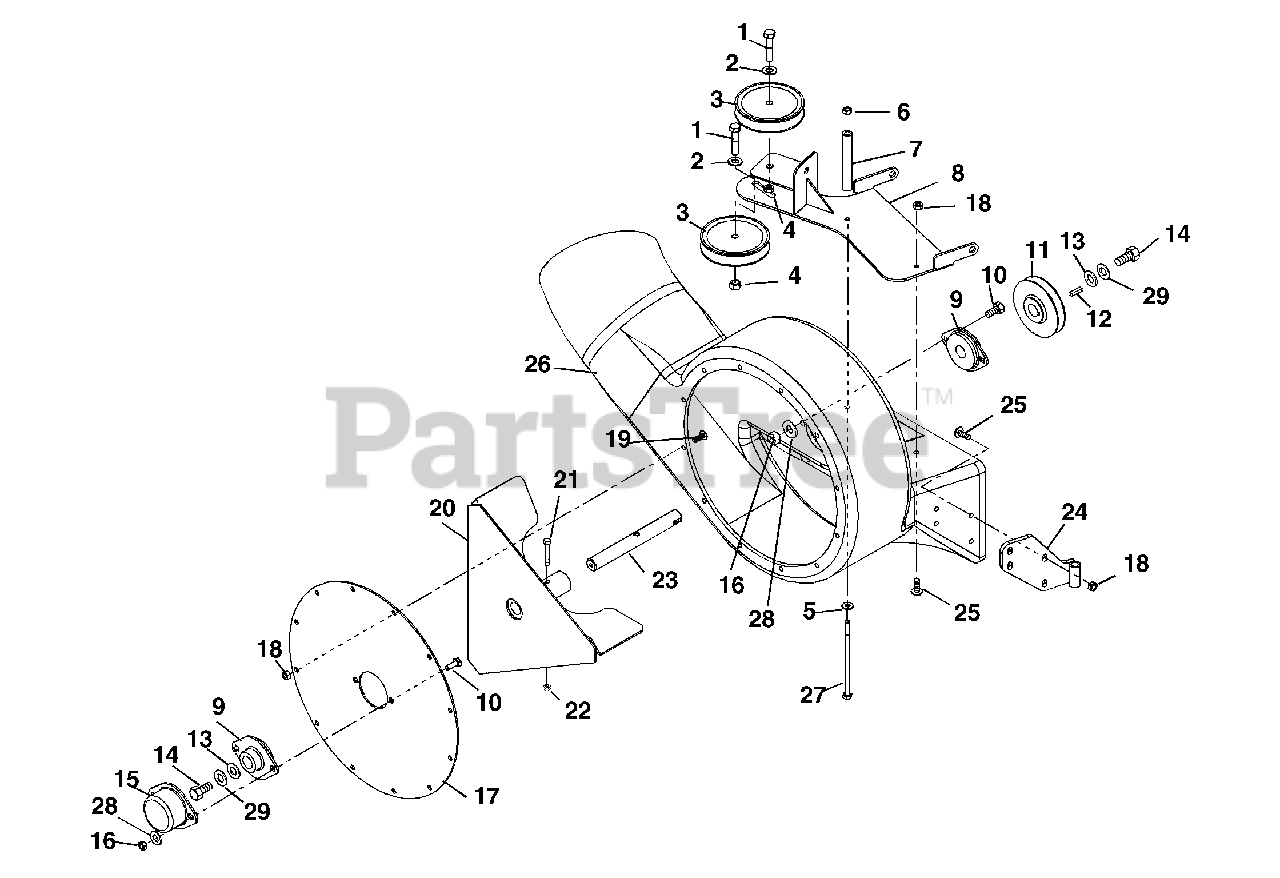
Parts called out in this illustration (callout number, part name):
1	Bolt-Hex .38-16 x 1.50 Grade 5
2	Washer-Flat-Steel .38 x .875 x .083
3	Idler-V 3.00 x .38
4	Nut-Locking-Flange .38-16
5	Washer-Flat-Steel .281 x .62 x .065
6	Nut-Locking-Center .25-20
7	Spacer-.334 I.D. x .500 O.D. x 4.625
8	Bracket-Complete Mule Assembly
9	Bearing, 2 Bolt Flange-.75 ID
10	Bolt-Hex .31-18 x 1.00 Grade 5
11	Pulley, Driven 3.50
12	Key-Square .187 x .50 x .187
13	Washer-.328 x 1.0 x .094
14	Bolt-Hex .25-28 x .75 Grade 5
15	Cover-Bearing
16	Nut-Locking-Nylon .312-18
17	Plate-Bearing Mount
18	Nut-Locking-Flange .250-20
19	Screw-Machine .250-20 x .50
20	Impeller-Grass Pump
21	Bolt-Hex .25-20 x 1.50 Grade 5
22	Nut-Locking-Center .25-20
23	Shaft, Grass Pump
24	Weldment, Mounting Bracket
25	Screw-Machine .25-20 x .75
26	Housing-Grass Pump
27	Bolt-Hex .25-20 x 6.00 Grade 5
28	Washer-Flat-Steel .312 x .734 x .065
29	Washer-Lock .25 x .062
